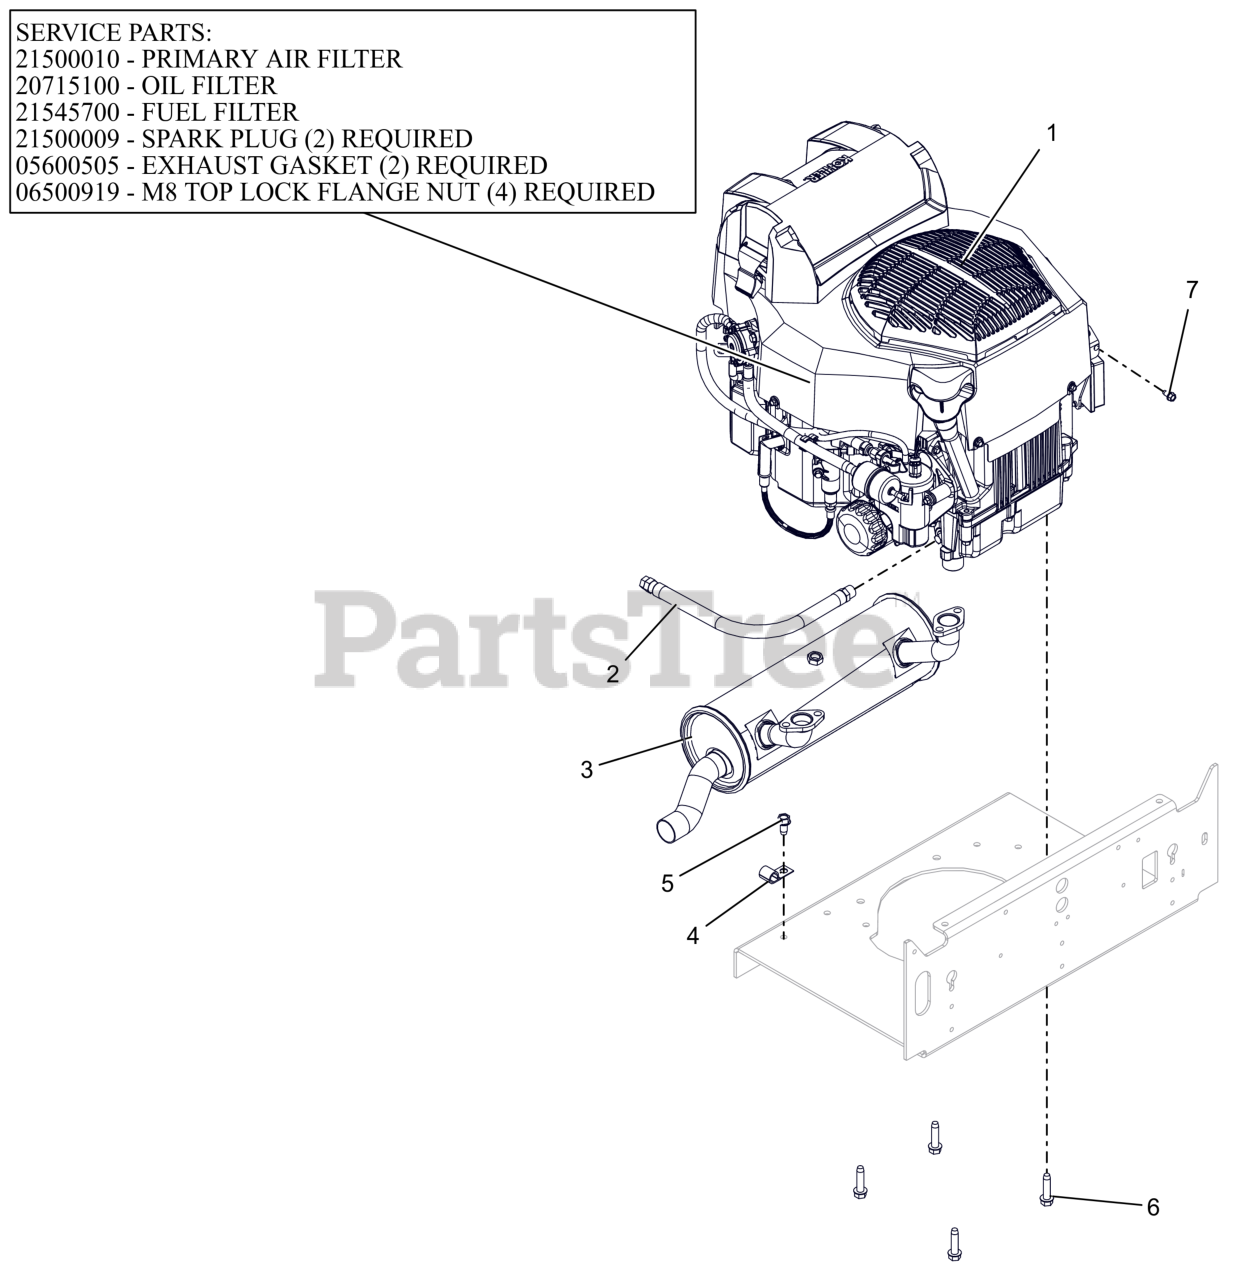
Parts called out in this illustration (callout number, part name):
1	ENGINE, KOHLER EZT725 EFI
1	AIR CLEANER, KOHLER CONFIDANT
1	OIL FILTER KOHLER
1	FILTER-FUEL KOHLER COURAGE PRO
1	PLUG, SPARK KOHLER
1	GASKET, MUFFLER KOHLER TWIN
1	NUT-LK-TOP-FLG M8 ZCC
2	HOSE, OIL DRAIN
3	MUFFLER, ZT725/740 EFI
5	SCR,TAP .375-16X.75 HWH TR ZCC
6	SCR-TAP .38-16X1.50 HWH ZCC
7	SCR-TAP .25-20X.50 HWH ZCC
